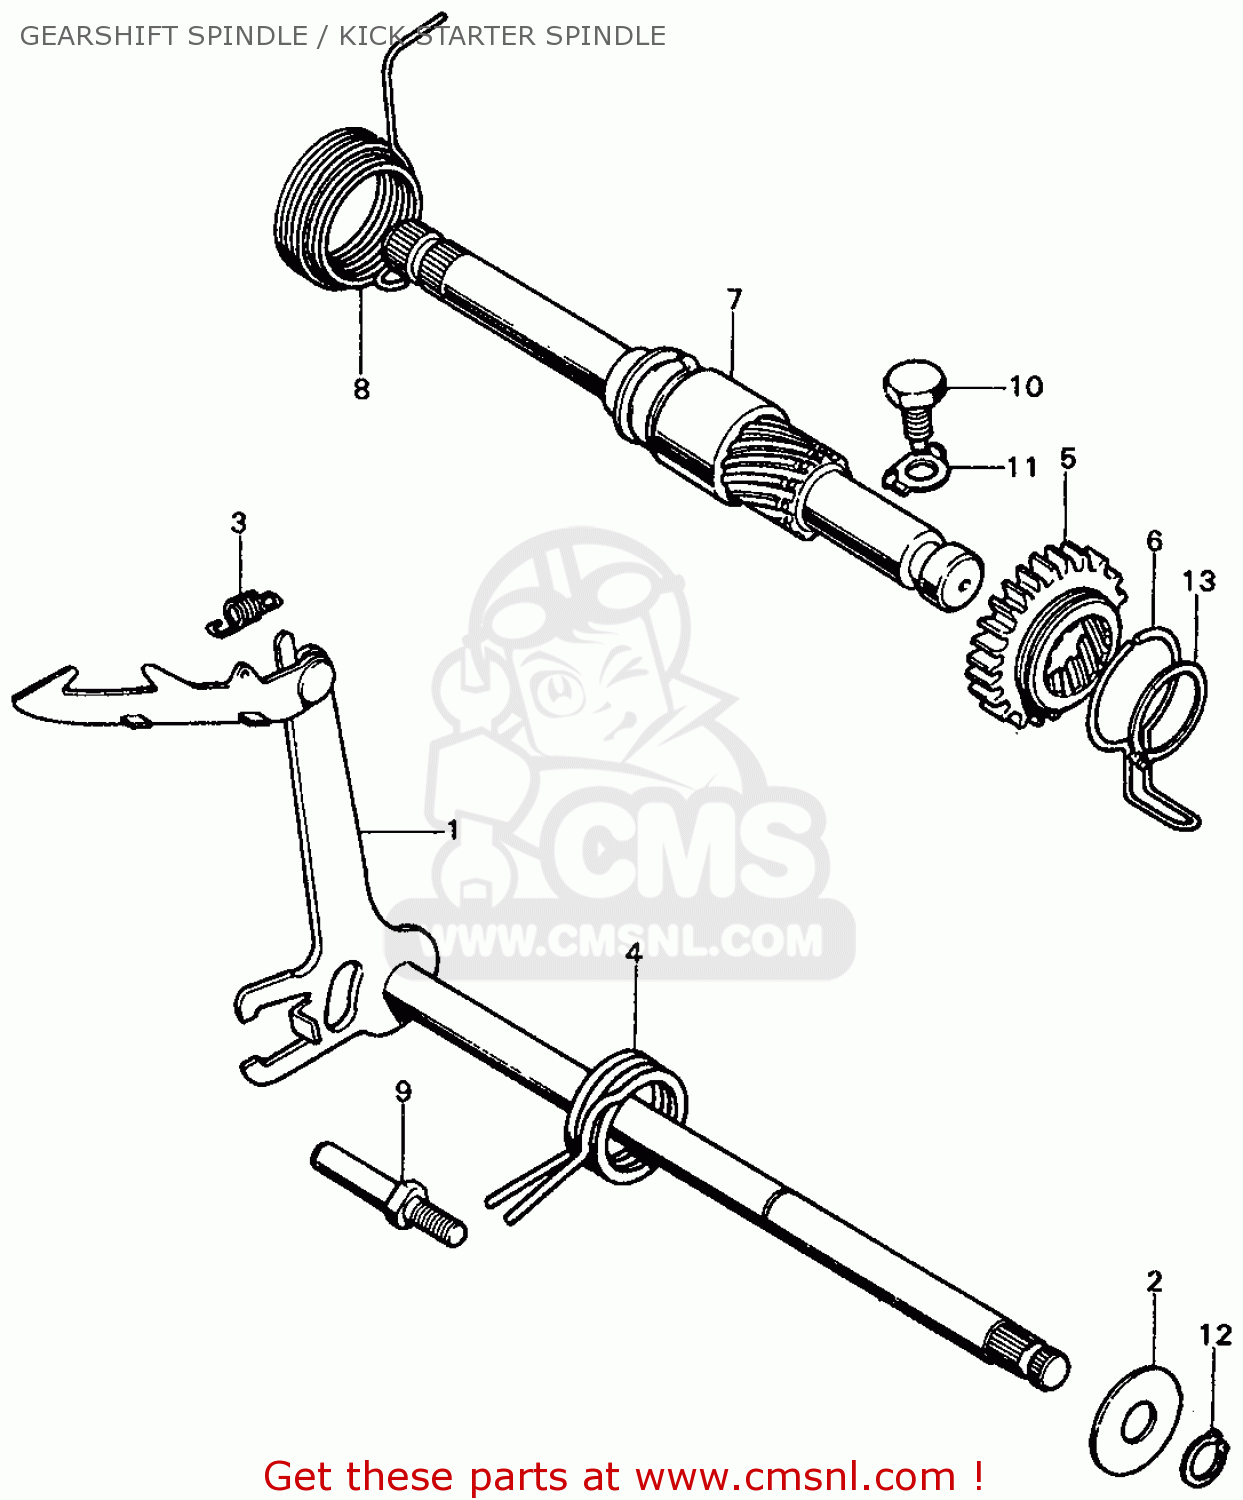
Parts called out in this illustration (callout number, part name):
1	SPINDLE,GEARSHIF
2	STOPPER SPINDLE
3	SPRING,SHIFT ARM
4	SPRING,GEARRETURN
5	PINION,KICK
6	SPRING,FRICTION
7	SPINDLE,COMP,KICK
8	SPRING,STARTER
9	PIN,RETURN SPRING
10	BOLT 8 MM
11	WASHER 8 MM
12	CIRCLIP,EX,12
13	CIRCLIP, 25M/M
